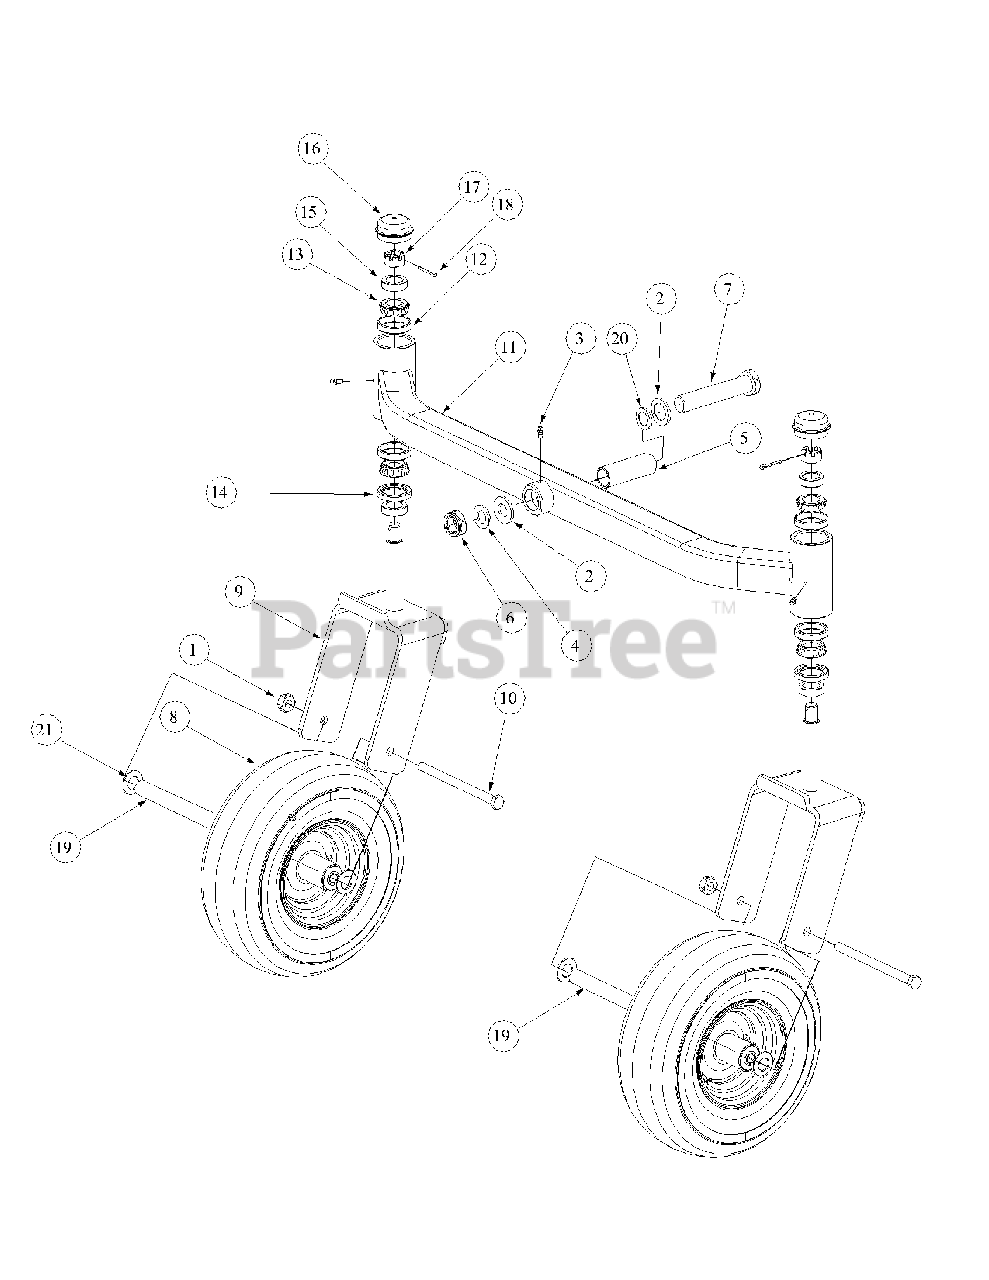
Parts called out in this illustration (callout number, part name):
1	Nut, 1/2-20, Center Lock
2	Bell Washer, 1.25 ID
3	Grease Fitting
4	Special Washer
5	Spacer, 1.005 ID x 1.25 OD x 3.6
6	Nut, Jam, 1.0-14, Insert Lock
7	Hex Cap Screw, 1-14 x 5.0
8	Wheel, 13 x 6.50 x 6, White
8	Retainer Flange
8	Roller Bearing
9	Yoke, Caster Wheel
10	HHCS, 1/2-20, 7.50
11	Front Axle Assembly
12	Cup Bearing
13	Bearing Cone
14	Seal
15	Ring Seal
16	Grease Cap, 1.986 OD
17	Slotted Nut, 3/4-16
18	Cotter Pin, 5/32, 1.25
19	Wheel Spacer
20	Flat Washer, 1.25 ID
21	Spacer, .812 ID x .218 LG
